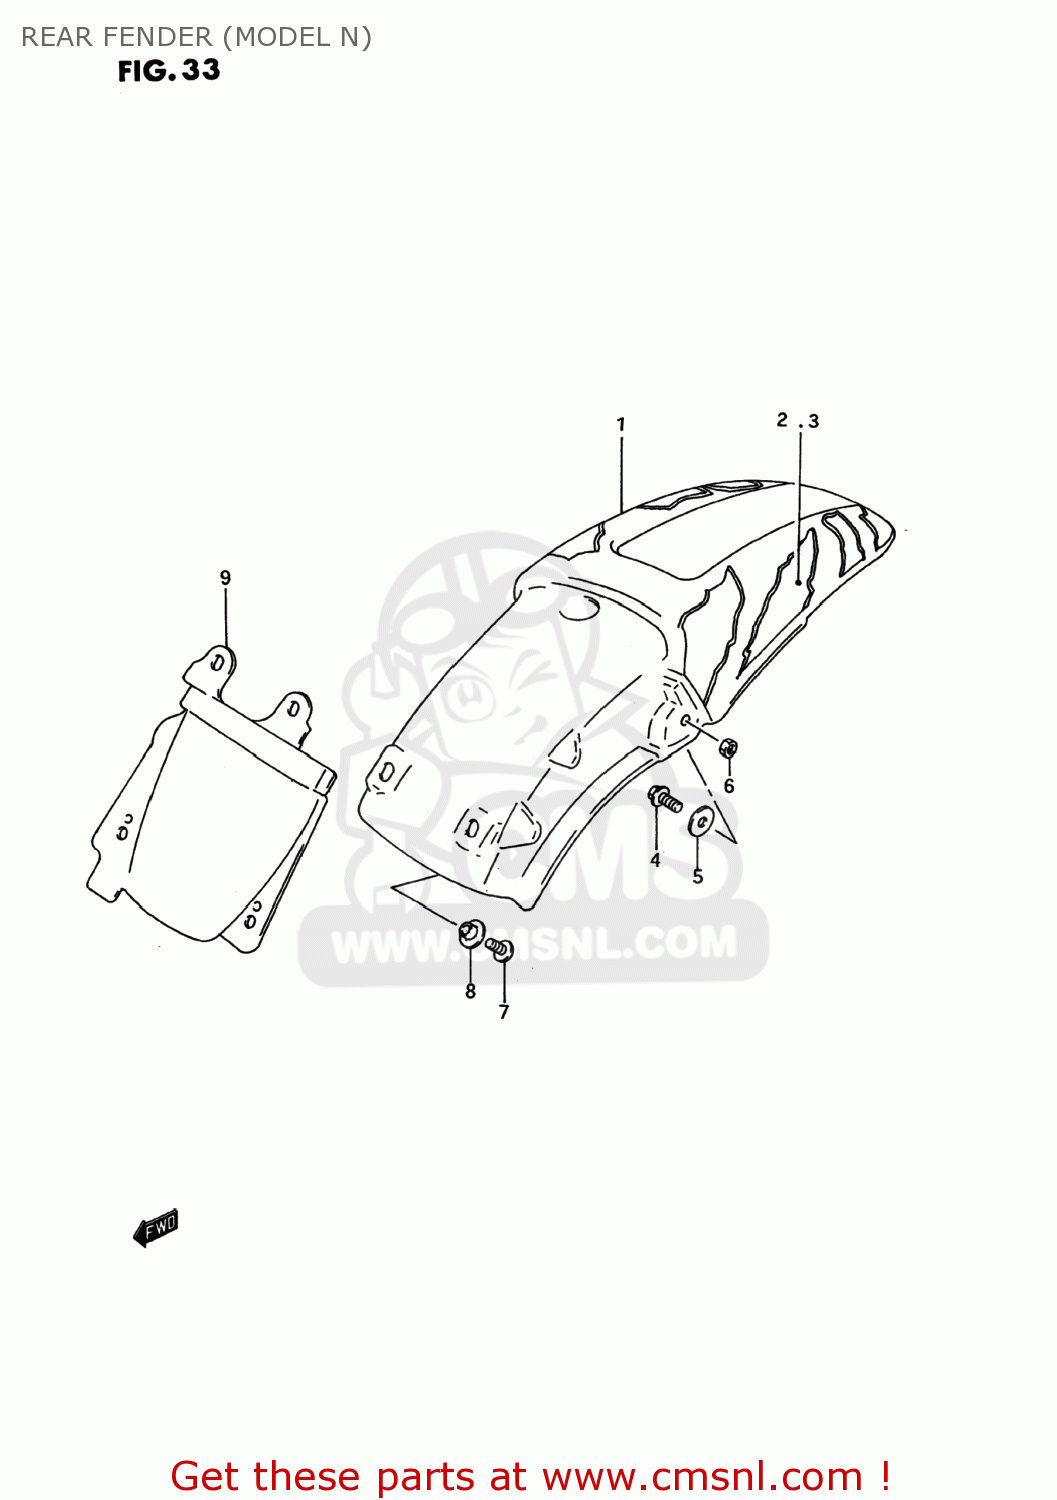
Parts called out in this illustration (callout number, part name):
1	BODY,RR FENDER
2	EMBLEM,REAR FENDER,RIGHT
3	EMBLEM,REAR FENDER,LEFT
4	BOLT
5	WASHER (6.5X29X1.6)
6	NUT 6MM
7	SCREW
8	WASHER
9	MUD GUARD,REAR FENDER,FRONT
